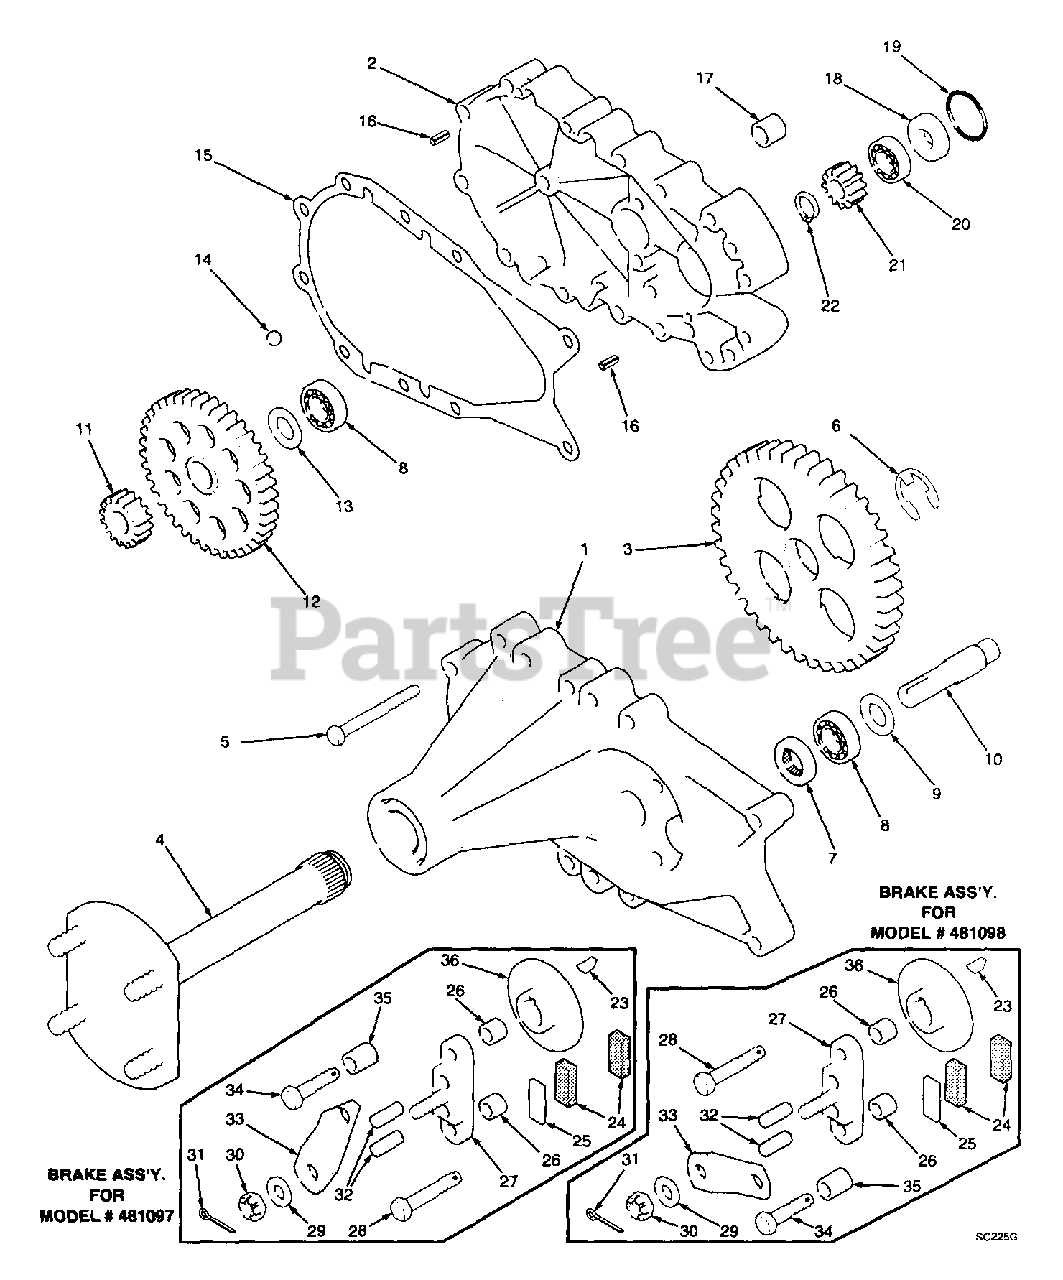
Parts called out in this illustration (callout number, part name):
1	Axle Housing Assembly
2	Hydro Mount Housing
3	Splined 72 Tooth Final Drive Gear
4	Axle Shaft Assembly
5	Bolt, 1/4-20 x 2-1/2" Hex Head
6	E-Ring .875
7	Oil Seal, 1.25 x .625
8	Ball Bearing, .62 ID x 1.38 x .44
9	Washer, HT .62 ID x 1.0 OD x .05 Thick
10	Brake Shaft (Splined)
11	Splined Reduction Gear, 17 Tooth
12	Splined 60 Tooth Gear
13	Washer, HT .62 ID x 1.0 OD x .05 Thick
14	Ball, 3/8" Diameter
15	Gasket, Housing
16	Pin, Spring 3/16" x 1/2" x 12" Long
17	Mounting Spacer
18	Bearing, Spacer
19	O-Ring
20	Ball Bearing, 15mm x 35mm x 11mm
21	Input Gear, 11 Tooth
22	Retaining Ring
23	Key, Hi Pro 3/16 x 5/8
24	Puck, Brake
25	Plate, Puck
26	Brake Spacer
27	Brake Yoke Assembly
28	Bolt, 1/4-20 x 1-1/2" W/Patch
29	Washer, 7/16 x 7/8 OD x .06 HT
30	Nut, Castle 5/16-24 PL
31	Pin, Cotter
32	Pin, Brake Actuating
33	Arm, Brake Actuator (LH Assy.)
33	Arm, Brake Actuator (RH Assy.)
34	Bolt, 1/4-20 x 2-1/2"
35	Spacer, Torsion Spring
36	Disc, Brake
